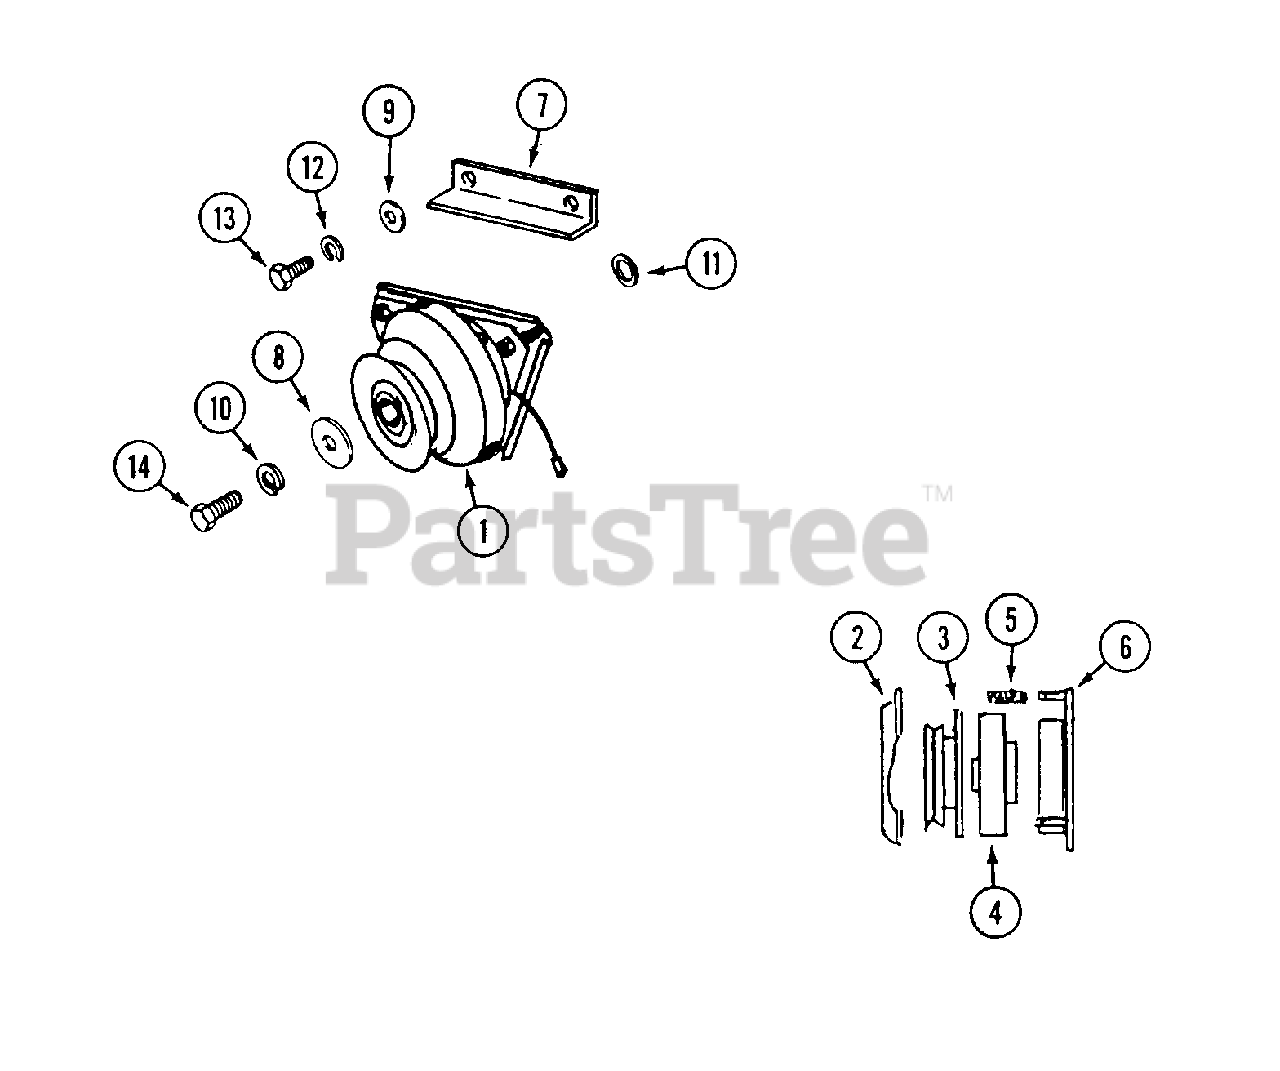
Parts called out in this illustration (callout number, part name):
1	CLUTCH ASSEMBLY
2	BRAKE - clutch
3	ARMATURE - clutch
4	ROTOR - clutch
5	KIT - spring and nut
6	COIL - clutch
7	BRACKET - clutch stop
8	WASHER - retaining
9	WASHER - .438" x 1"
10	LOCKWASHER - 3/8"
11	WASHER - 1-1/8"
12	LOCKWASHER - 7/16"
13	BOLT - 7/16" - 14 x 3/4"
14	BOLT - 3/8" - 24 x 1-1/2"
